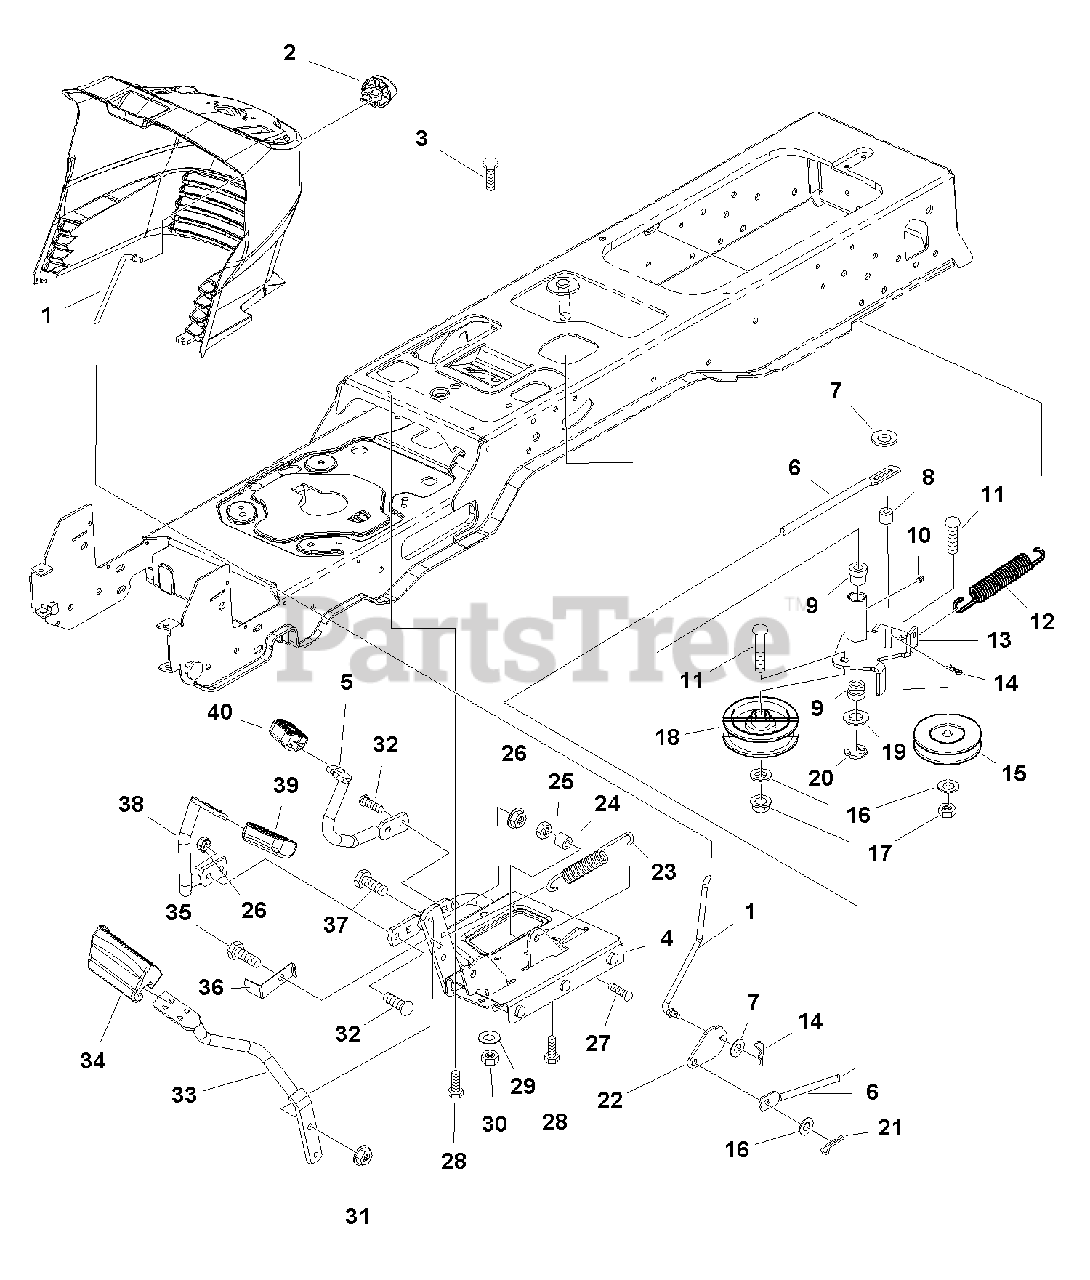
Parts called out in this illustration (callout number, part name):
1	ROD, Brake
2	KNOB, Push On, Red
3	CAPSCREW, Hex Head Flange Lock, 5/16-18 x 3/4
4	PEDAL ASSEMBLY
5	PEDAL, Reverse
6	ROD, Brake (Flat Ends)
7	WASHER
8	SPACER, (Earlier Only)
9	BUSHING
10	FITTING, Lube, Ball Check
11	CARRIAGE BOLT, 3/8-16 x 1-3/4
12	SPRING, Extension
13	ARM & HUB ASSEMBLY, (Later, Does use Ref. No. 8)
13	ARM & HUB ASSEMBLY, (Earlier, Requires Ref. No.8 )
14	PIN, Quick
15	PULLEY ASSEMBLY, 3" OD, W/Bearing
16	WASHER
17	NUT, Hex Lock ESNA, 3/8-16
18	PULLEY,Idler, 2-3/4 OD
19	WASHER
20	RING, Clipring
21	PIN, Cotter
22	LATCH, Brake
23	SPRING, Extension
24	CAM, Roller
25	NUT, Hex Lock ESNA, 1/4-20
26	NUT, Hex KEPS, 5/16-18
27	CARRIAGE BOLT, 1/4-20 x 1-1/4
28	CAPSCREW, Hex Head Taptite, 5/16-18 x 3/4
29	WASHER
30	NUT, Hex Lock ESNA Light, 5/16-18
31	NUT, Hex Flange Lock, 5/16-18
32	CARRIAGE BOLT, 5/16-18 x 7/8
33	PEDAL, Brake
34	PAD, Brake Pedal
35	CAPSCREW, Hex Head Taptite, 3/8-16 x 3/4
36	ACTUATOR, Switch
37	CAPSCREW, Hex Head, 5/16-18 x 1
38	PEDAL, Forward
39	PAD, Foot Pedal Forward
40	PAD, Foot Pedal Reverse
